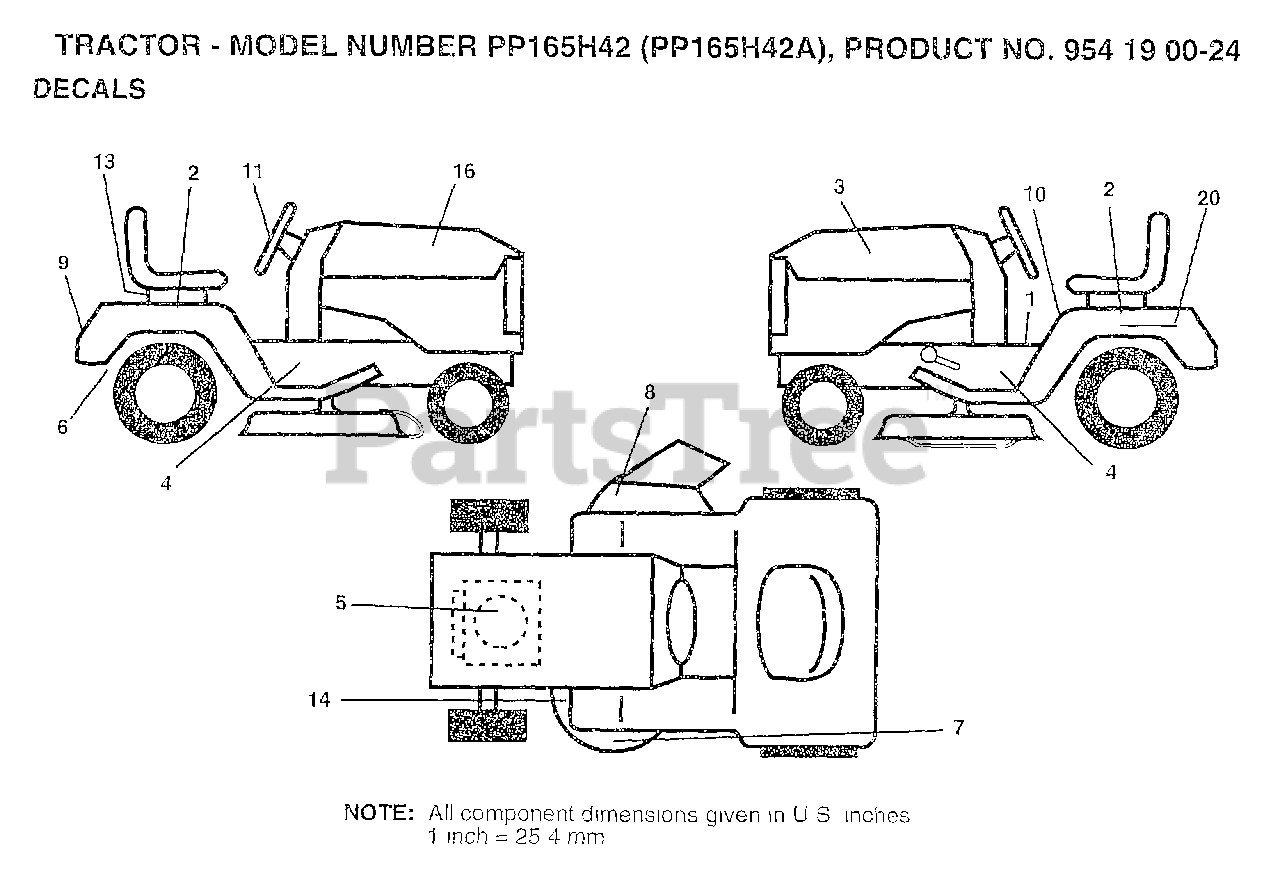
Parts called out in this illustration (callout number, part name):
1	"DECAL FENDER,OPER"
2	DECAL FENDER AUTO
3	DECAL.HOOD.LH
4	DECAL.CHASSIS
5	DECAL HP ENGINE
6	DECAL DRAWBAR LH
7	"DECAL,ENVIRO DECK"
8	"DECAL, WARNING"
9	DECAL.FENDER.BELT.GUARD
10	DECAL.CAUT.ENG/FR
11	DECAL INS STRG WH
13	RETAINER-SPRING
14	"DECAL-SCHEM,BELT"
16	DECAL.HOOD.RH
20	DECAL.BATRY.3-3908
